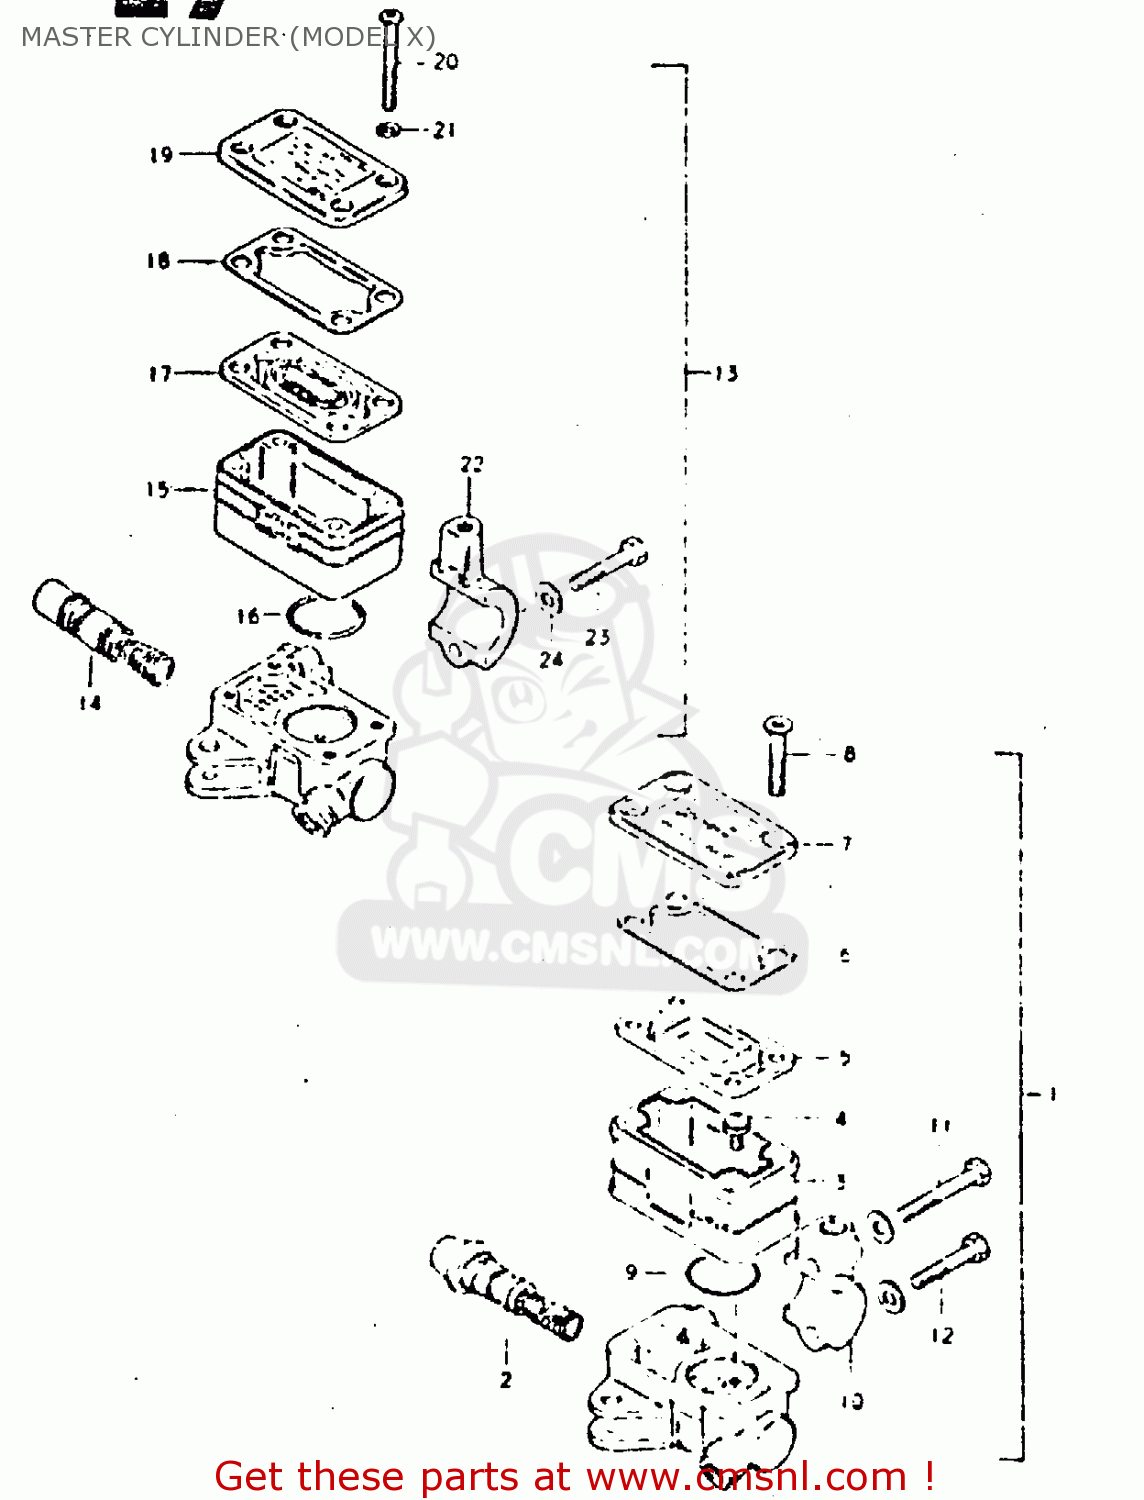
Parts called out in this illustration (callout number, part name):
1	CYLINDER ASSY, MASTER
2	PISTON & CUP SET
3	RESERVOIR
4	SCREW,MASTER C
5	DIAPHRAGM
6	PLATE,DIAPHRAGM
7	CAP
8	SCREW
9	O RING
10	HOLDER
11	BOLT,MASTER CYLINDER H
12	BOLT,MASTER CYLINDER H
13	CYLINDER ASSY, MASTER
14	PISTON & CUP SET
15	RESERVOIR
16	O RING
17	DIAPHRAGM
18	PLATE,DIAPHRAGM
19	CAP
20	SCREW
21	WASHER
22	HOLDER
23	BOLT
24	WASHER
